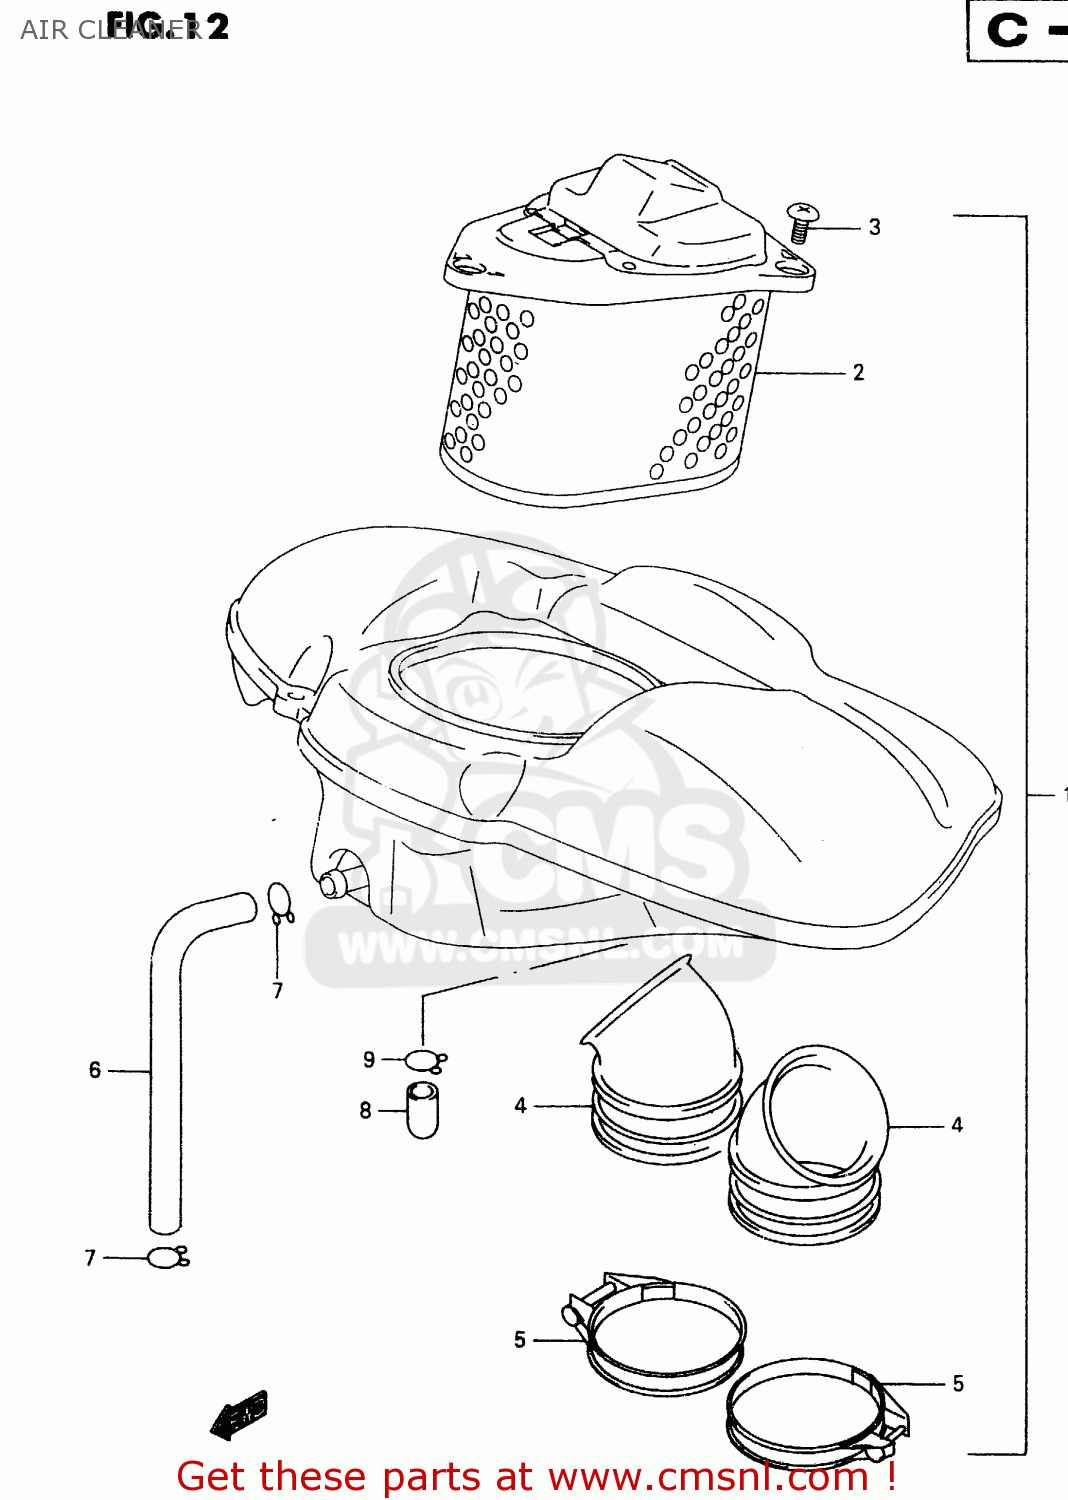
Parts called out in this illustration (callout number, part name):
1	CLEANER ASSY,AIR
2	FILTER,AIR CLEANER
3	SCREW 5X12
4	TUBE,OUTLET
5	CLAMP
6	TUBE,BREATHER
7	CLIP
8	PLUG
9	CLIP
